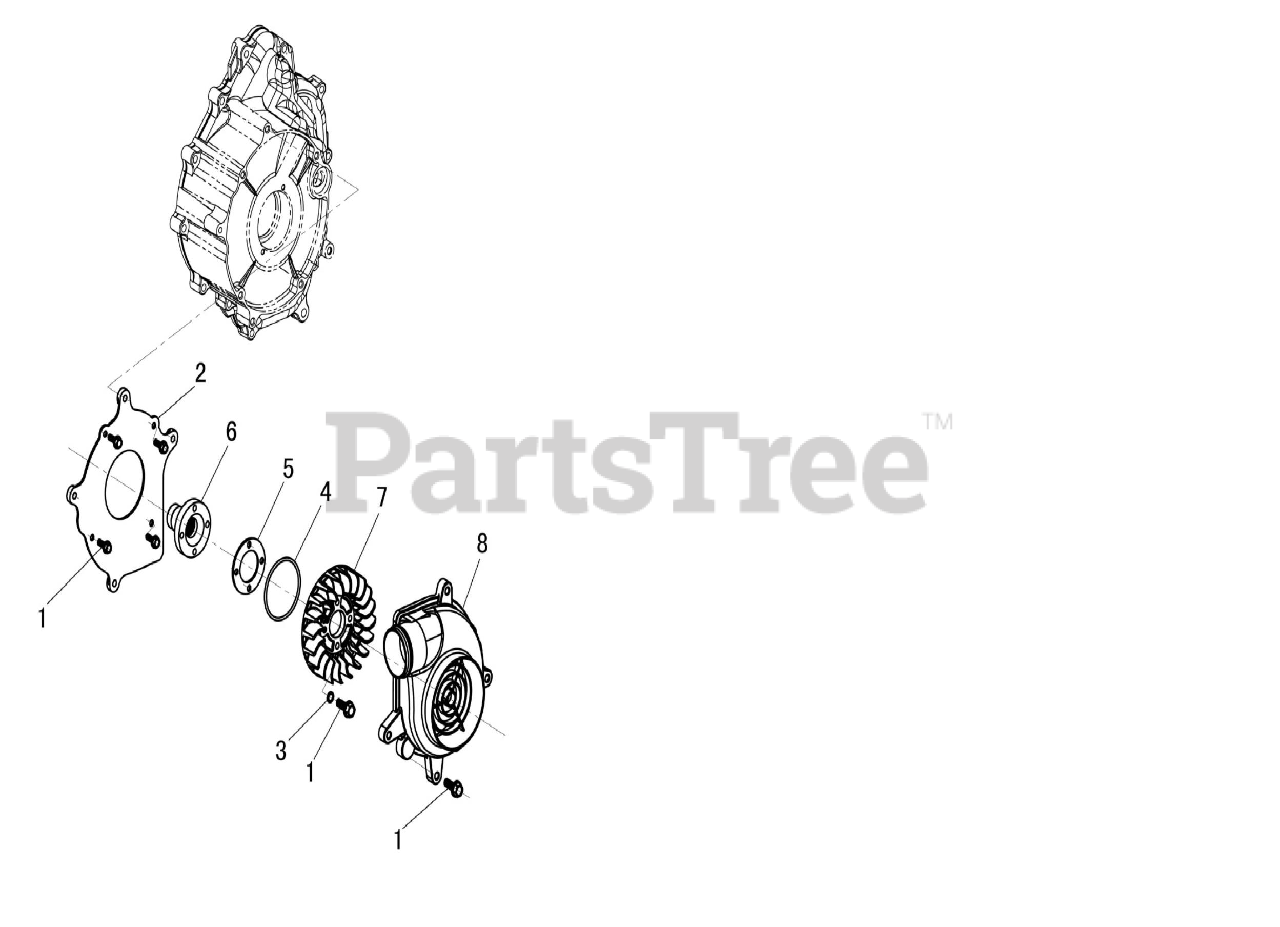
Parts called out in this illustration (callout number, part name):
1	Hex flange bolts M6X20
3	Washer 6X11X1.5
4	O-Ring 64.4X3.1
5	Fan Strongback
6	Starting Driven Pulley
8	Fan Cowl
